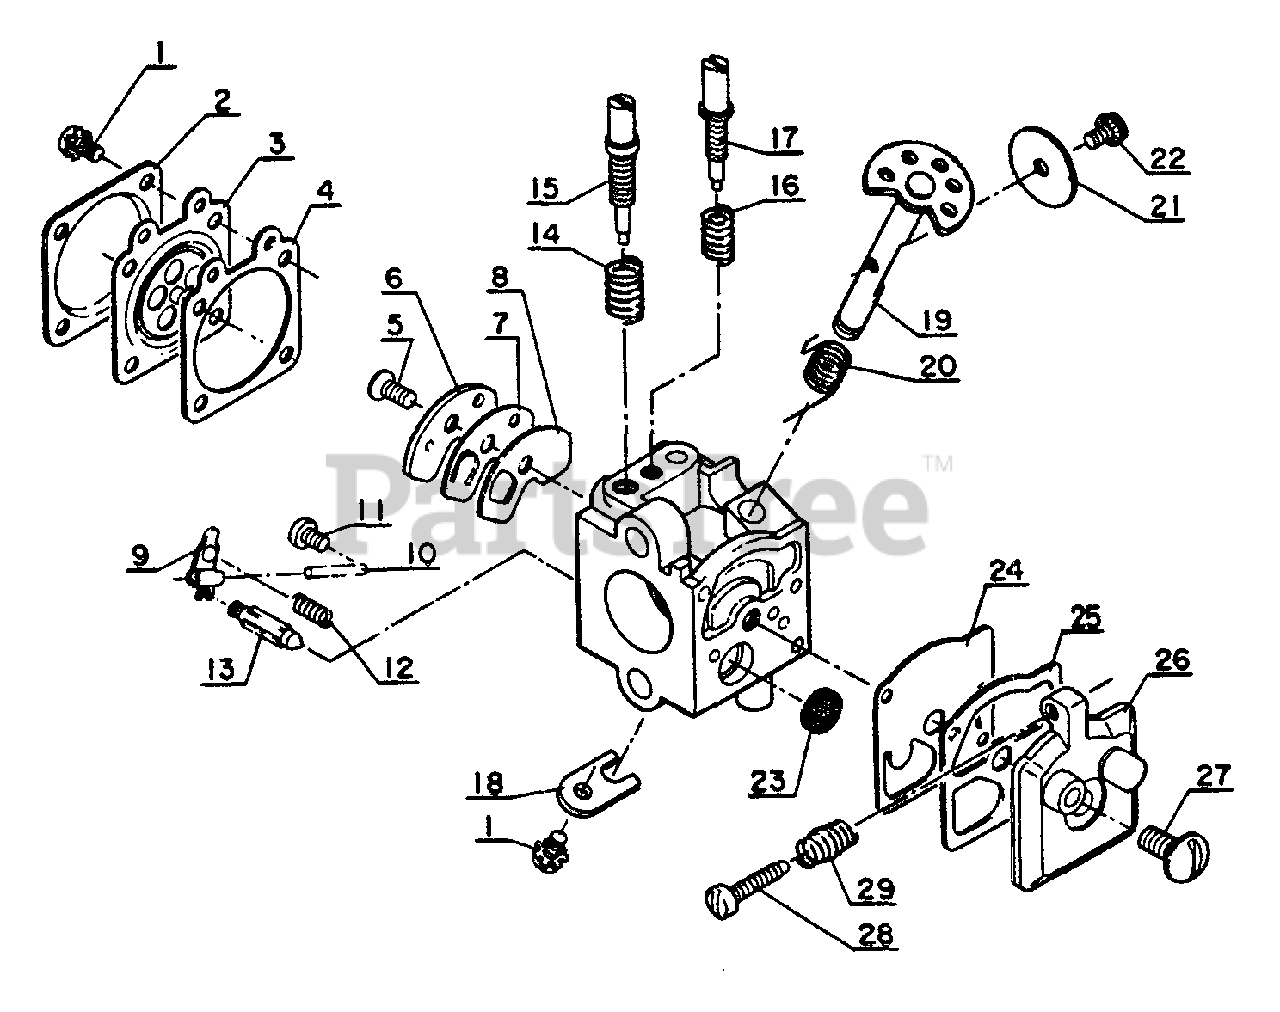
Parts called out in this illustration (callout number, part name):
2	COVER, METERING DIAPHRAGM
3	DIAPHRAGM, METERING
4	GASKET, METERING DIAPHRAGM
5	SCREW, CIRCUIT PLATE
6	PLATE, CIRCUIT
7	VALVE, CHECK
8	GASKET, CIRCUIT PLATE
9	LEVER, METERING
10	PIN, METERING LEVER
11	SCREW, METERING LEVER PIN
13	VALVE, INLET NEEDLE
14	SPRING, NEEDLE
15	NEEDLE, HIGH SPEED
16	SPRING, NEEDLE
17	NEEDLE, LOW SPEED
18	CLIP, THROTTLE SHAFT
19	SHAFT, THROTTLE
20	SPRING, THROTTLE RETURN
21	VALVE, THROTTLE
23	STRAINER
24	DIAPHRAGM, FUEL PUMP
25	GASKET, FUEL PUMP
26	COVER, PUMP
28	SCREW, IDLE ADJUST
29	SPRING, IDLE ADJUST
